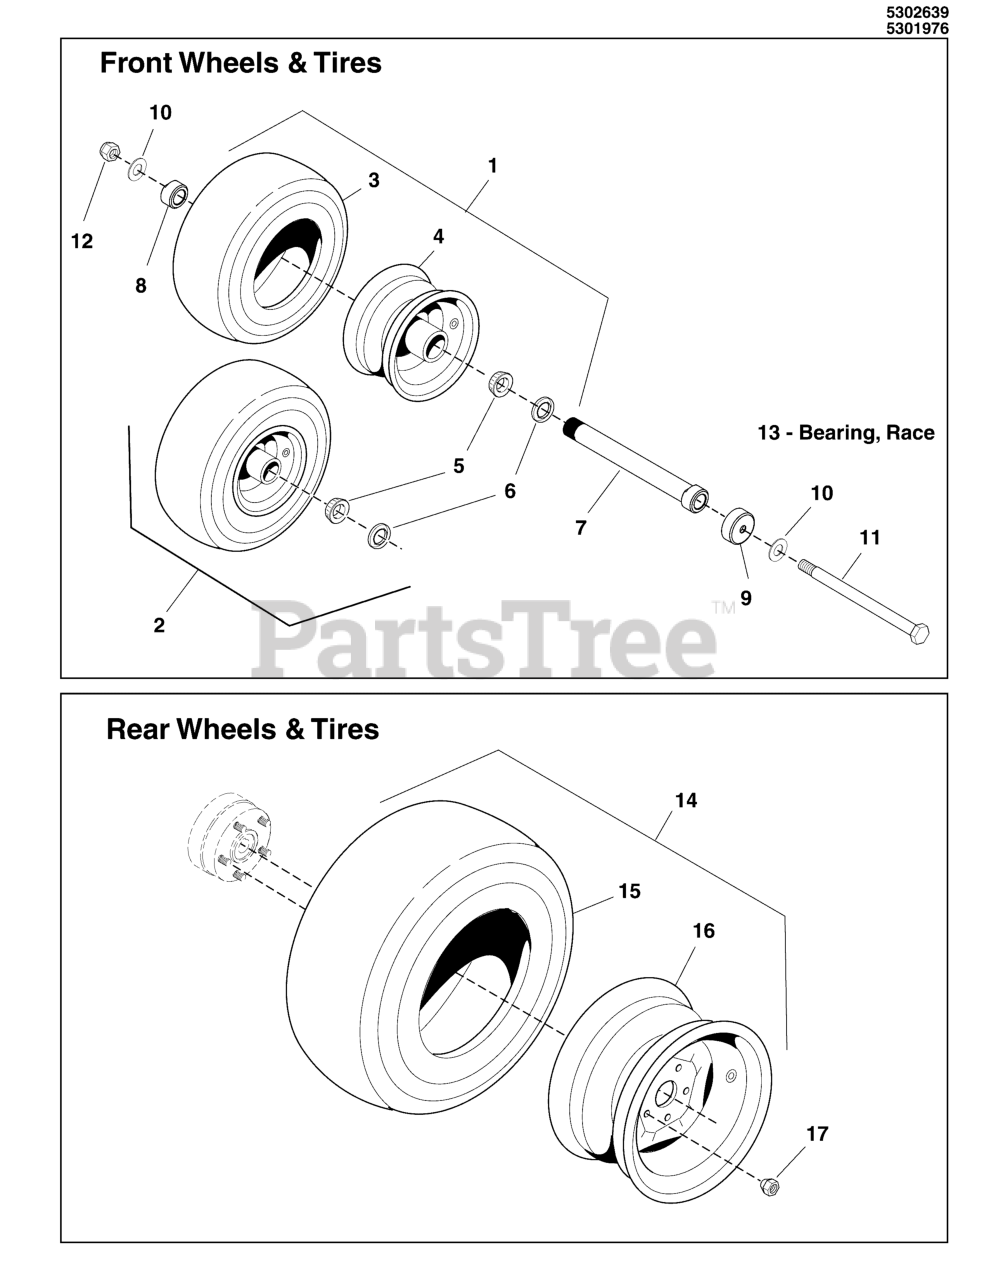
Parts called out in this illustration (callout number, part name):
1	TIRE ASSM, 13 X 6.5 - 6, PNE / TB
2	TIRE ASSM, 13 X 6.5 - 6, FF / TB
3	TIRE, RUBBER ONLY
4	WHEEL ASSEMBLY, FOR 13 X 6.5 X 6 TIRES (INCLUDES BEARING AND SEALS)
5	BEARING, Tapered Roller
6	SEAL, GREASE
7	BEARING ADJUSTER, SPACER, 7.062 LG
8	NUT, BEARING ADJUSTER, AXLE
9	DEBRIS, COVER, CASTER WHEELS
10	WASHER, 1/2 SAE
11	BOLT, 1/2-13 X 9" GD5 YZ
12	NUT, Hex Flange, Nylock, 1/2-13
13	BEARING, RACE
14	TIRE/WHEEL ASM, 24 X 12.00-12, TURF SMART
14	TIRE WHEEL ASM, 24X12.00-12, TURF MASTER
15	TIRE, 24X12.00-12, TURF SMART
15	TIRE, 24 X 12 X 12
16	WHEEL, 12 X 8.5
17	NUT, 1/2-20, FOR WHEEL BOLT SILVER
